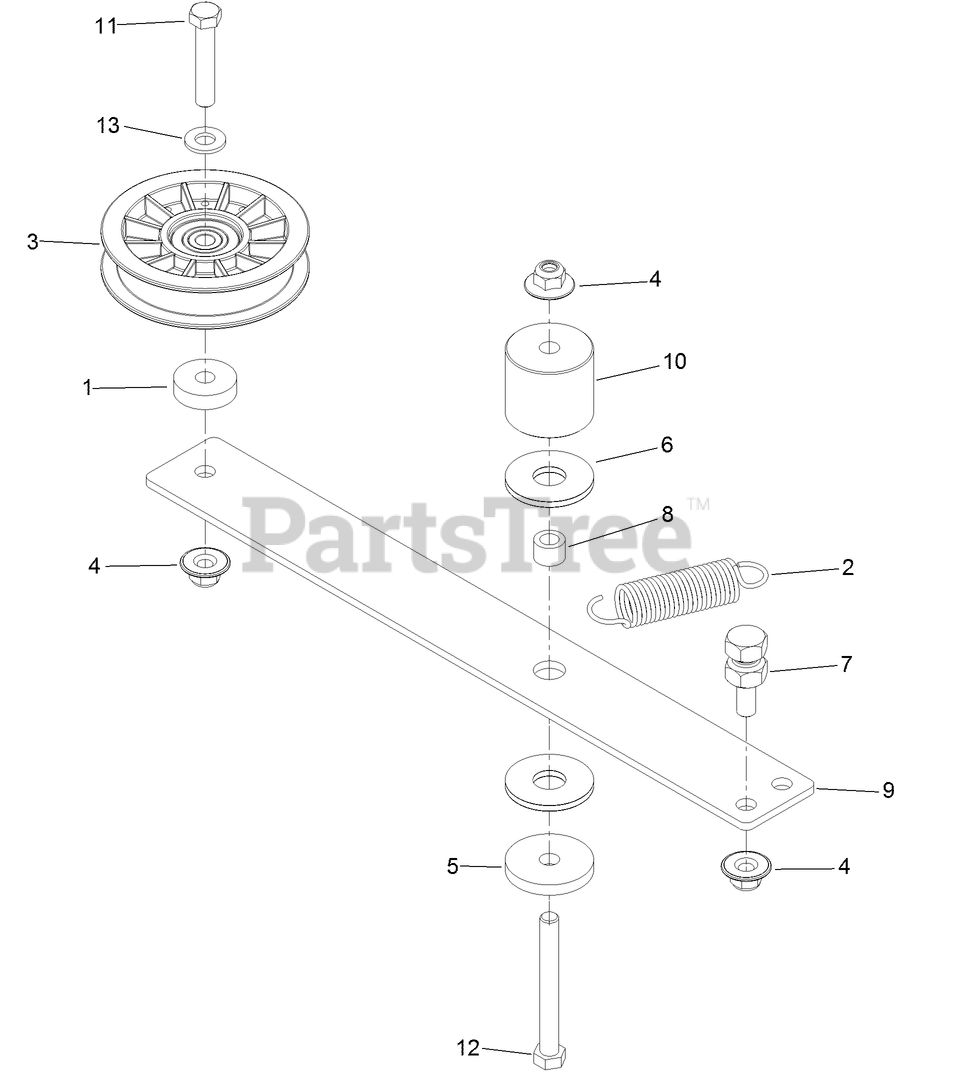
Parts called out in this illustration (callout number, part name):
1	Spacer
2	SPRING-EXTENSION
3	PULLEY-IDLER, FLAT
4	NUT-FLANGE, NI
5	WASHER-PLAIN
6	WASHER-FRICTION, COMPOSITE
7	ANCHOR-SPRING, SHORT
8	SPACER
9	ARM-IDLER, HYDRO
10	SPACER-PLAIN
11	SCREW-HH
12	SCREW-HH
13	WASHER-FLAT
